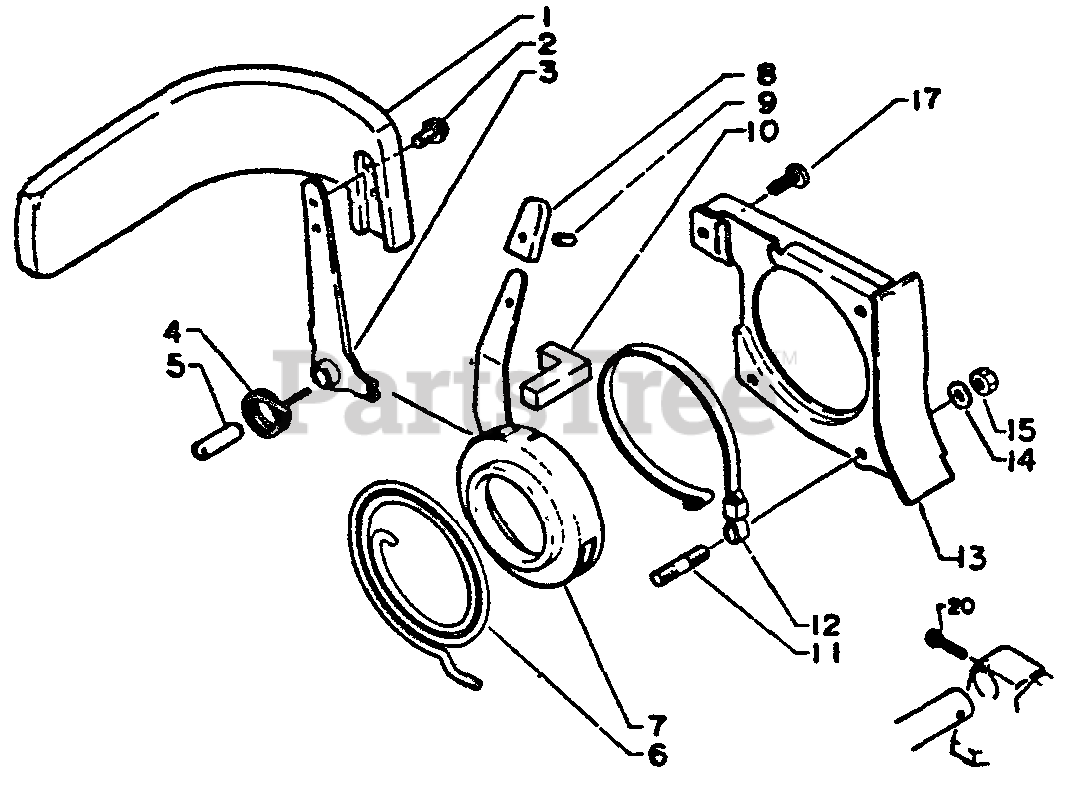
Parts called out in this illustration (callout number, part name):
1	HANDLE, BRAKE
2	SCREW 4×12
3	LEVER, BRAKE
6	SPRING, BRAKE
7	CASE, BRAKE BAND
9	PIN, SPRING - 3×8
10	SEAL, DUST
11	STUD
12	BAND, BRAKE
13	PLATE, SEAL
14	WASHER 4.2×16.5×1
17	SCREW 4×10
20	SCREW 4×20
